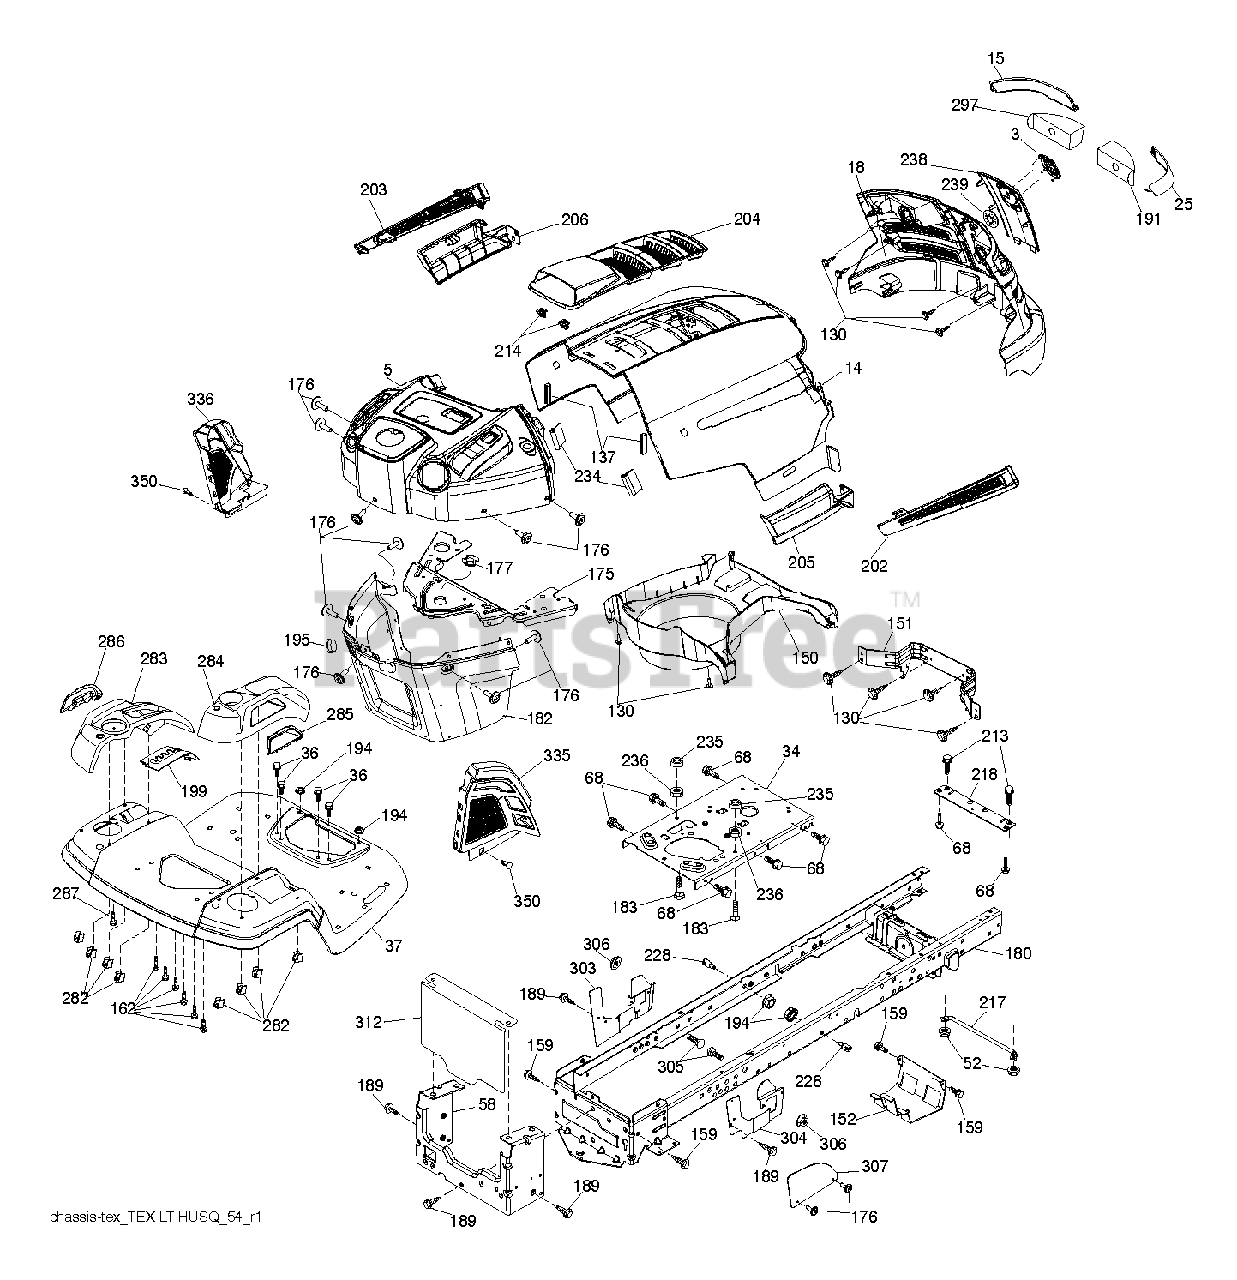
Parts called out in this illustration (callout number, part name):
3	RP LOGO
5	SUBASM.DASH.UPPER.HLT.498
14	HOOD.HUSQVARNA.LT.ORANGE
15	LENS.HUSQVARNA LT.RH
18	GRILLE.SVC.HUSQVARNA.GREY
25	LENS.HUSQVARNA LT.RH
34	PLATE PLATE ENGINE
36	SCREW 5/16"
37	FENDER.TLT.FS.W/CUPHLD.ORANGE
52	LOCKNUT
58	DRAWBAR UPPER 2PC SMALL FENDER
68	SCREW LT
130	SCREW.#10 X 0.750.BOS
137	BUMPER DASH
151	BRACKET PIVOT
152	SHIELD.BROWNING.PNT.GT.V2
159	SCREW, 3/8-16X3/4
162	SCREW.HI-LO.CONSOLE
175	CROSSMEMBER
176	SCREW.#10-24X5/8.RN.QU
177	BUSHING STEERING
180	CHASS.WLDMNT.TL.12GA/2P.48/54
182	DASH.LOWER.PREDATOR LT
183	BOLT.5/16-18X1-1/4 FULL THD
189	SCREW
191	INSERT.REFLECTIVE.RH.
194	NUT LOCK HEX FLANGE 5/16-18
195	PLUG.TEX.DASH.SVC.MINDER.GREY
199	PLATE.DECK.LIFT.HUSQ.LT
202	VENT.SIDE.HUSQVARNA.LT.RT
203	VENT.SIDE.HUSQVARNA.LT.LFT
204	SUBASM.TOP.VENT.HUSQ.LT
205	SKIRT.SIDE.HUSQVARNA.LT.RT
206	SKIRT.SIDE.HUSQVARNA.LT.LEFT
213	BOLT
214	CLIP.RETAINER.TINNER.
217	ROD.PIVOT.HOOD
218	X-PIECE.HOOD.STOP.NON/
228	STUD.FASTNER.W/ANTI-ROTATE
234	BUMPER.HOOD.TEX.HUSQVARNA
235	SPACER FENDER
236	NUT.CENTERLOCK.5/16-
238	TRIM.HUSQ LT.668
282	CLIP.RETAINER.CONSOLE.LT.HUSQ
283	CONSOLE.ASM.LFT.RSF.HUSQ.LT
284	CONSOLE CONSOLE.HUSQ.SHIFT.HYD
285	CONSOLE INSERT RH
286	CONSOLE.INSRT.LH.HUSQ.LT.BLACK
287	SCREW 1/4X20
297	INSERT REFLECTIVE
303	SHIELD CHASSIS LEFT
304	SHIELD CHASSIS RIGHT
306	NUT LOCK FLG 3/8-16 UNC
307	SHIELD UPPER PEDAL
312	SHIELD.PNT.DRAWBAR.FRENCH
335	COVER.LOWER.DASH.RH.BLACK
336	COVER-LH.LOWER.DASH.GT2.BLACK
350	CLIP.X-MAS.TREE
